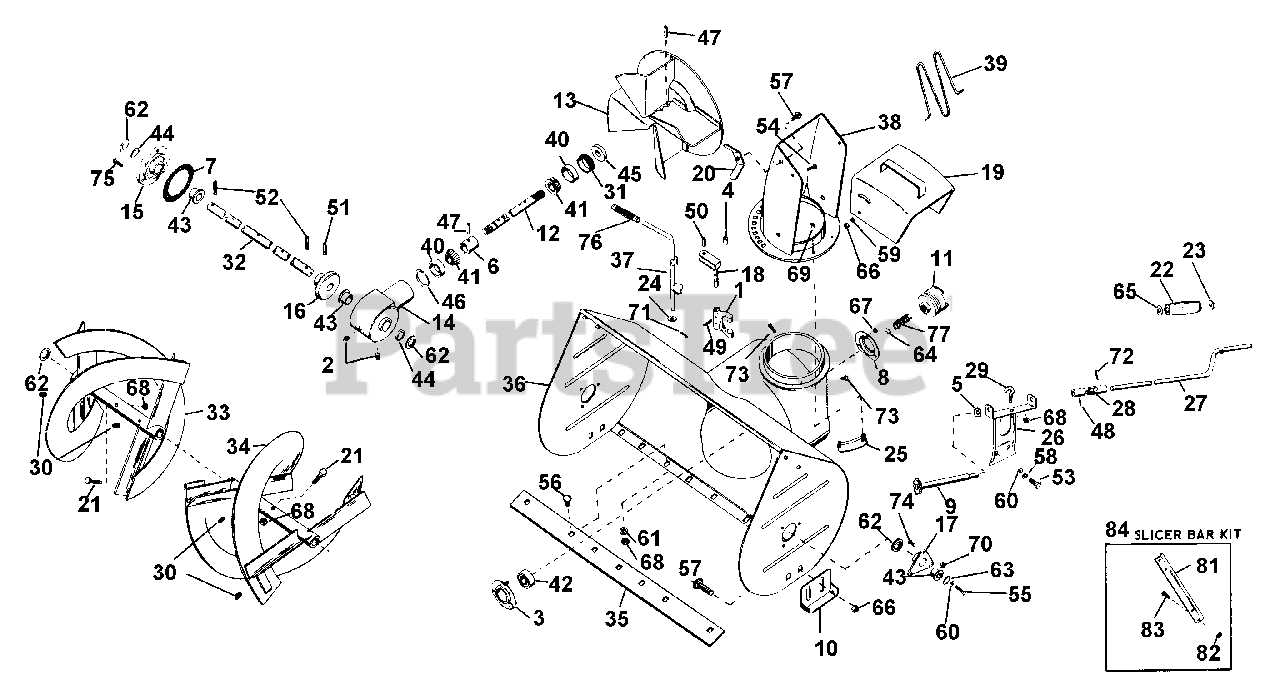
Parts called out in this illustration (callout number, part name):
1	CLUTCH FORK
2	PIPE PLUG
3	BEARING FLANGE
5	WAVE WASHER .531X.781X.125FH
6	BEARING SPACER
8	BEARING FLANGE
9	CONTROL SPROCKET
10	RUNNER
11	JAW CLUTCH
12	HELICON PINION SHAFT
14	CASE, GEAR - C.I.
15	GEAR CASE FLANGE
16	HELICON GEAR - 41 TOOTH
17	BEARING SUPPORT
18	FORK SHAFT
19	DEFLECTOR CHUTE
20	WING NUT
21	SHEAR BOLT YWZC
23	CAP, 3/8 ROD YWZC
24	WAVE WASHER .406X.750X.063FH
25	CHUTE CLAMP
26	CHUTE CNTL BRACKET
27	CHUTE CNTL CRANK
28	UNIVERSAL JOINT
30	HYDRAULIC DRIVE FITTING
31	ADJUSTMENT PLUG
32	FRONT GEAR SHAFT
33	R H RAKE
34	L H RAKE
35	SCRAPER BLADE
36	BLOWER HOUSING
37	FORK CAM
38	DISCHARGE CHUTE
39	SAFETY WIRE
40	BRG-CUP 1.781X.475
41	BRG-CONE .750X.61
42	BRG-BALL .750X1.750X.50
43	BSHG-FLG 1.000X1.12X.62X1.50BR
44	SEAL 1.000X1.312X.150
45	SEAL .750X1.499X.225
46	RG-RTNG INT 1.781 HSG X.062
47	PIN-ROLL .250X1.25
48	PIN-ROLL .125X1.00
49	PIN-ROLL .188X1.00
50	PIN-ROLL .313X1.25
51	PIN-ROLL .313X1.38
52	PIN-ROLL .188X1.50
53	BLT-HEX .31-18X.75 PL GR2
54	BLT-HEX .38-16X.75 PL GR2
55	BLT-HEX .50-13X1.00 PL GR2
56	BLT-RDHDSQSHNK .31-18X.50 YZ
57	BLT-RDHDSQNK .38-16X.75 SHT PL
58	WSHR-LK .312X.097 PL HVY
59	WSHR-LK .375X.115 HVY PL
60	WSHR-LK .500X.151 HVY PL
61	WSHR-FL-STL .38X.875X.083 PL
62	WSHR-FL-STL 1.010X1.505X.062PL
63	WSHR-FL-STL .511X1.441X.125 PL
64	WSHR-FL-STL .755X1.375X.062 PL
65	WSHR-FL-STL .382X.812X.023 PL
66	NUT-LK-CTR .375-16 GR A PL
67	NUT-LK-CTR .250-20 PL
68	NUT-LK .312-18 GR A PL
69	NUT-KEPS 10-24 PL
70	NUT-LK-FLG .250-20 PL
71	PIN-COTR .12X1.0 PL
72	PIN-COTR .12 X 1.25 PL
73	BLT-SCRHFWH .38-16X.50 PL
74	SCR-SLTR-SERNK .25-20X.62 PL
75	BLT-SERHFWH .25-20X.75 PL
77	SG-COMP .105X1.35X1.984
78	SNO-THRO DECAL
79	CAUTION LABEL
80	CLUTCH INSTRUCTION DECAL
81	CUTTER BAR
82	BLT-RDHDSQSHNK .31-18X.50 YZ
83	NUT-LK .312-18 GR A PL
84	SLICER BAR KIT
